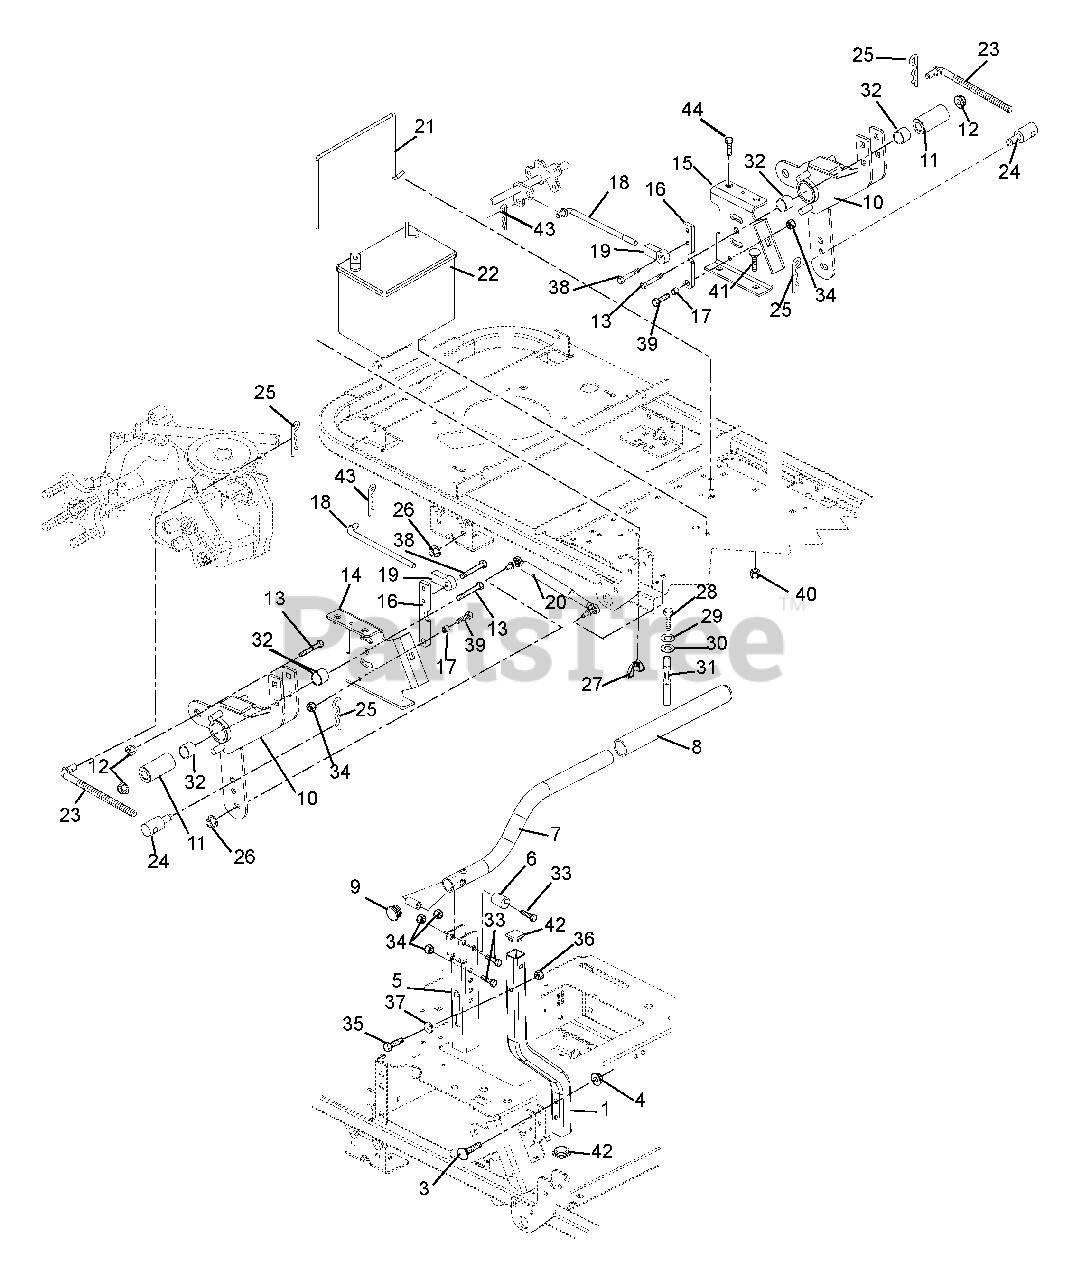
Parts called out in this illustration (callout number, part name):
1	Control Arm
2	Caplug, Square 1-14-20
3	Bolt, Round Head Square Neck .31-18 x 1.75 Grade 5
4	Nut, Locking Top Flange .31-18
5	Channel, Handlebar Adjustment
6	Eccentric
7	Handlebar
8	Grip, Handlebar
9	Caplug, Handlebar
10	Control Weldment
12	Nut, Locking Top Flange .50-13
13	Bolt, Hex .50-13 x 3.00 Grade 5
14	Weldment, Control RH
15	Weldment, Control LH
16	Bracket, Neutral Stop
17	Spacer, Neutral Stop
18	Link, Brake Rod
19	Rod End .38 RH
21	Battery Rod
22	Battery (12 Volt, 330 CCA, 50 Min. Reserve Cap.)
23	Link, Wireform
24	Pivot, Rod
25	Pin, Hair
26	Nut, Locking Top Flange 8 x 1.25
27	Nut, Locking Wing .25-20
28	Bolt, Hex .31-18 x 1.00 Grade 5
29	Washer-Locking .31 x .078 Regular
30	Washer-Flat-Steel .344 x .688 x .065
32	Bearing, 1.00 x 1.12 x .750
33	Bolt, Hex .31-18 x 1.75 Grade 5
34	Nut, 5/16-18 Flange Nyloc
35	Bolt, Hex .25-20 x 1.75 Grade 5
36	Nut, Locking Nylon .250-20
37	Bushing, Flange .265 x .437 x .250 x .750
38	Bolt, Hex .38-16 x .75 Grade 5
39	Bolt, Hex .31-18 x 1.25 Grade 5
40	Nut, 3/8-16 Flange Nyloc
41	Bolt, Round Head Square Neck .38-16 x 1.00
42	Caplug, Square
43	Pin, Hair .08 x .18 x 1.18
44	Screw, Cap .38-16 x 2
